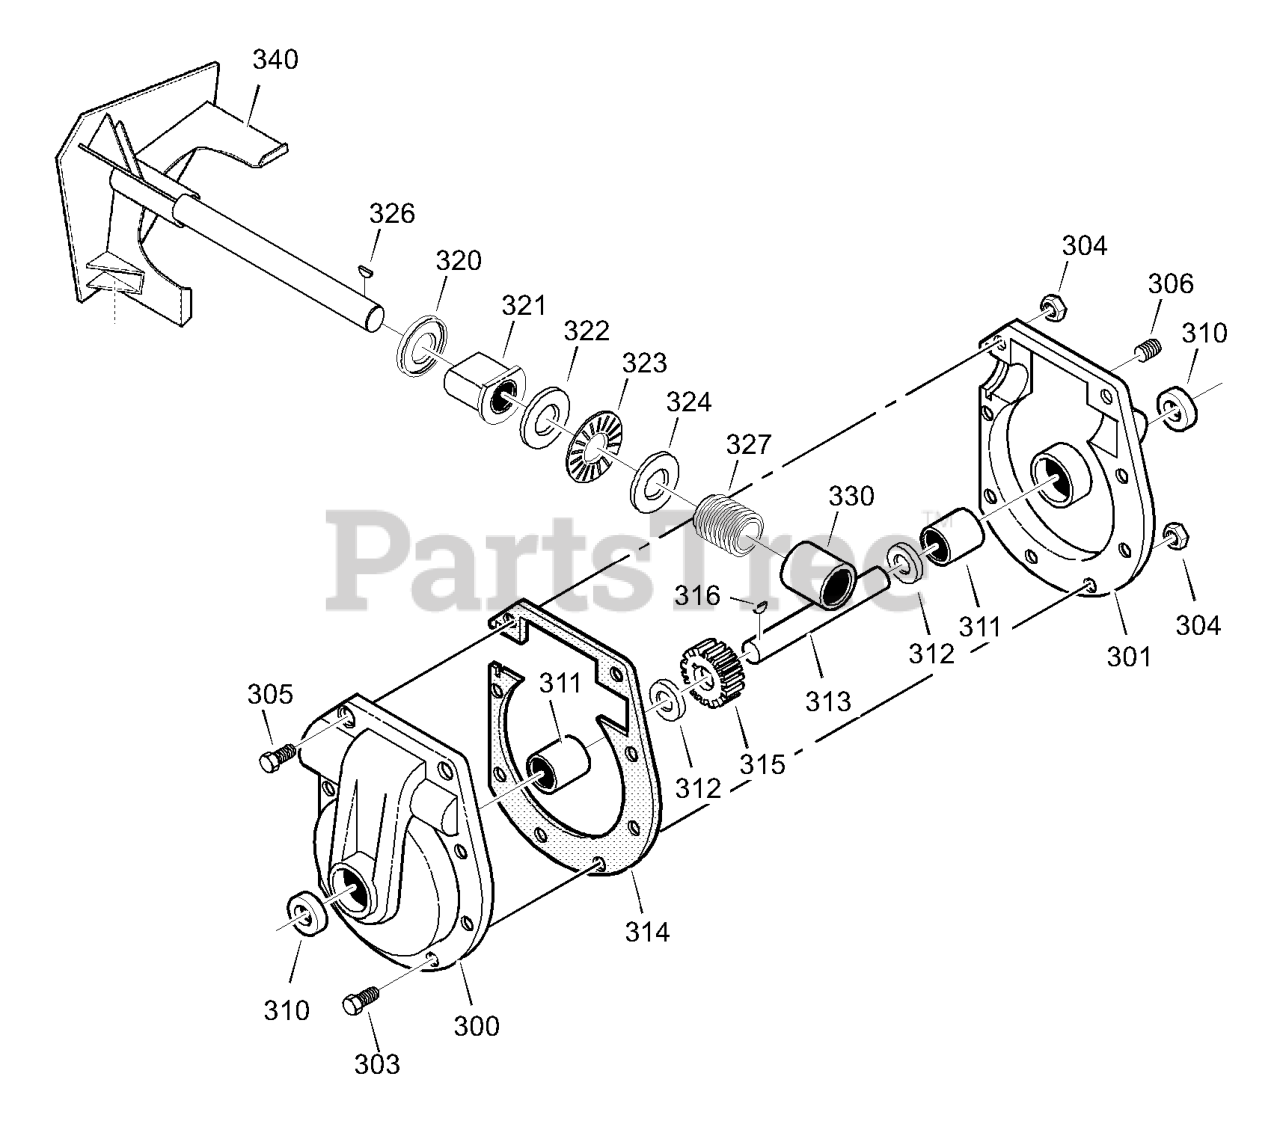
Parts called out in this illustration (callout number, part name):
300	CASE, GEAR, RH
301	CASE, GEAR, LH
303	SCREW, 5/16-24 x 1.00
304	NUT, 5/16-24
305	SCREW, 5/16-24 x 1.50
306	PLUG, PIPE 1/4-18
310	SEAL, OIL
311	BEARING, SLEEVE
312	WASHER, FLAT
313	SHAFT, AUGER OUTPUT
314	GASKET, GEAR BOX
315	WORM GEAR
316	KEY, WOODRUFF #61
320	RING, QUAD
321	BEARING, FLANGE
322	WASHER, FLAT
323	BEARING, ROLL
324	WASHER, FLAT
327	GEAR, WORM
330	BEARING, SLEEVE
340	IMPELLER
